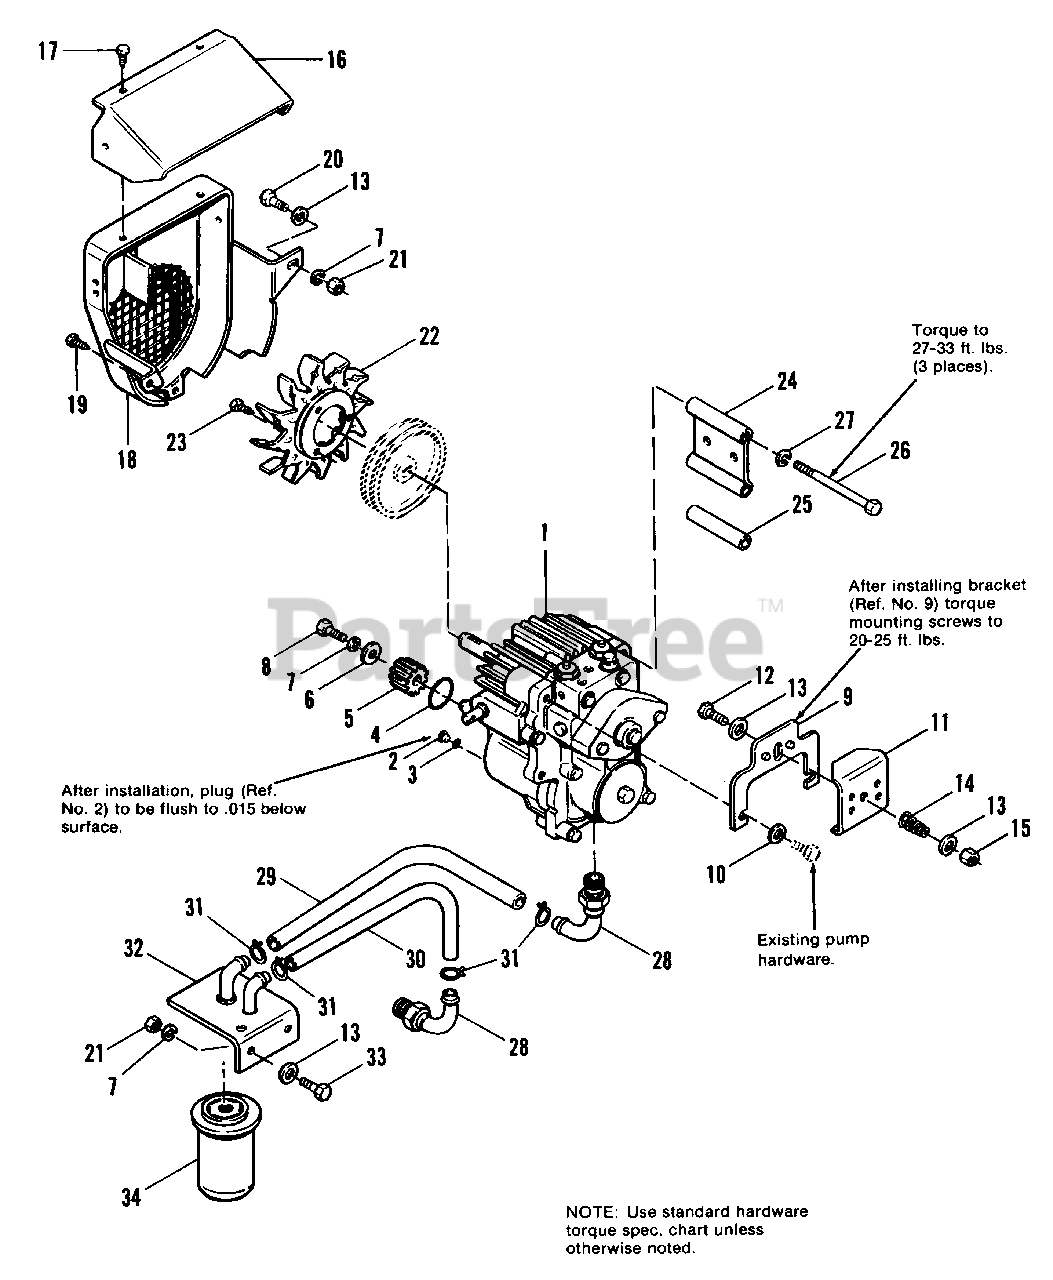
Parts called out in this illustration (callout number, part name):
1	HYDRO PUMP & MOTOR UNIT
5	PINION, Motor Shaft
7	LOCKWASHER, 5/16
8	CAPSCREW, Hex Hd., 5/16-18 x 3/4
11	LATCH, Release
12	CAPSCREW, Hex Hd., 5/16-18 x 1
13	WASHER, 5/16
15	LOCKNUT, Hex, 5/16-18
16	DEFLECTOR, Shroud
17	SCREW, Taptite #10-32 x 3/8
18	SHROUD ASSY. W/Screen
19	SCREW, Thd. Form., 5/16-18 x 1/2
20	CAPSCREW, Hex Hd., 5/16-18 x 3/4
21	NUT, Hex, Full, 5/16-18
22	FAN, Pulley
23	SCREW, Thd. Form., 1/4-20 x 3/8
25	SPACER
26	CAPSCREW, Hex Hd., 3/8-16 x 5
27	LOCKWASHER, 3/8
28	HOSE, Insert
31	CLAMP, Hose
32	SUPPORT ASSY., Oil Filter
33	CAPSCREW. Hex Hd., 5/16-18 x 7/8
34	FILTER ASSY.
